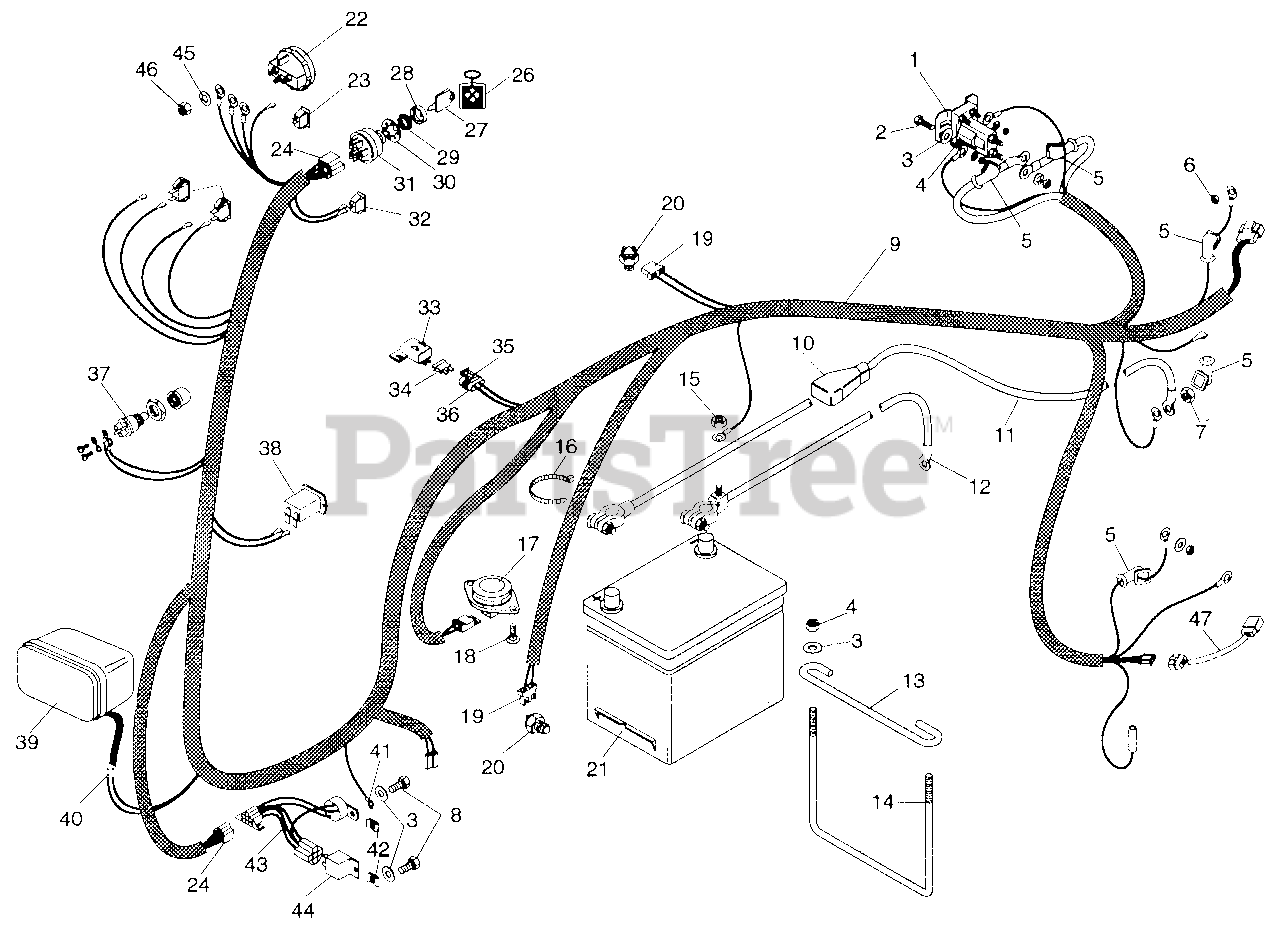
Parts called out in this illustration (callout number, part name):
1	SOLENOID
2	BLT-HEX .25-20 X .75 PL GR 5
3	WSHR-FL-STL .281 X .625 X .065
4	NUT-LK-NYL .250-20 PL
5	G-BOOT, INSULATOR
6	NUT-HEX M5 X .8 PL
7	NUT-HEX M8 X 1.25 PL
8	BLT-HEX .25-20 X .63
9	HRNS, WIRING 22/30-H
10	CVR, BATTERY TERMINAL
11	CBL, POSITIVE CABLE
12	CBL, NEGATIVE BATTERY
13	ROD, HOLD DOWN
14	ROD, BATTERY
15	NUT-HEX .312-18
16	TIE WRAP, BLACK
17	SEAT SWITCH
18	SCR-MCH .25-20 X .50
19	CONN, 2-WIRE SWITCH
20	SWITCH
21	BATTERY, 24 FLTV
22	GA, WATER TEMPERATURE
23	SWITCH, BLANK
24	CONNECTOR
25	LIGHT, INDICATOR
26	KEY CHAIN
27	IGNITION SWITCH KEY
28	CAP - IGNITION SWITCH
29	NUT - PANEL .562-24 GRECO
30	WSHR-LOCK INT .563 X .040 PL
31	IGNITION SWITCH
32	SWITCH, LIGHT
33	CVR
34	FUSE, 25 AMP
35	TERM., FOR 14-16 GA WIRE
36	ASM, CONN WEATHER TIGHT
37	SWITCH, PREHEATER
38	HOUR METER
39	HEADLAMP, 3 X 5 HALOGEN
40	TERMINAL, MALE
41	TERM., RING TONGUE
42	NUT-SPEED .25-20
43	MODULE, TIME DELAY
44	RELAY
45	WSHR-LOCK 10 X .047 MED PL
46	NUT-HEX 10-32
47	WIRE HARNESS, SOLENOID
